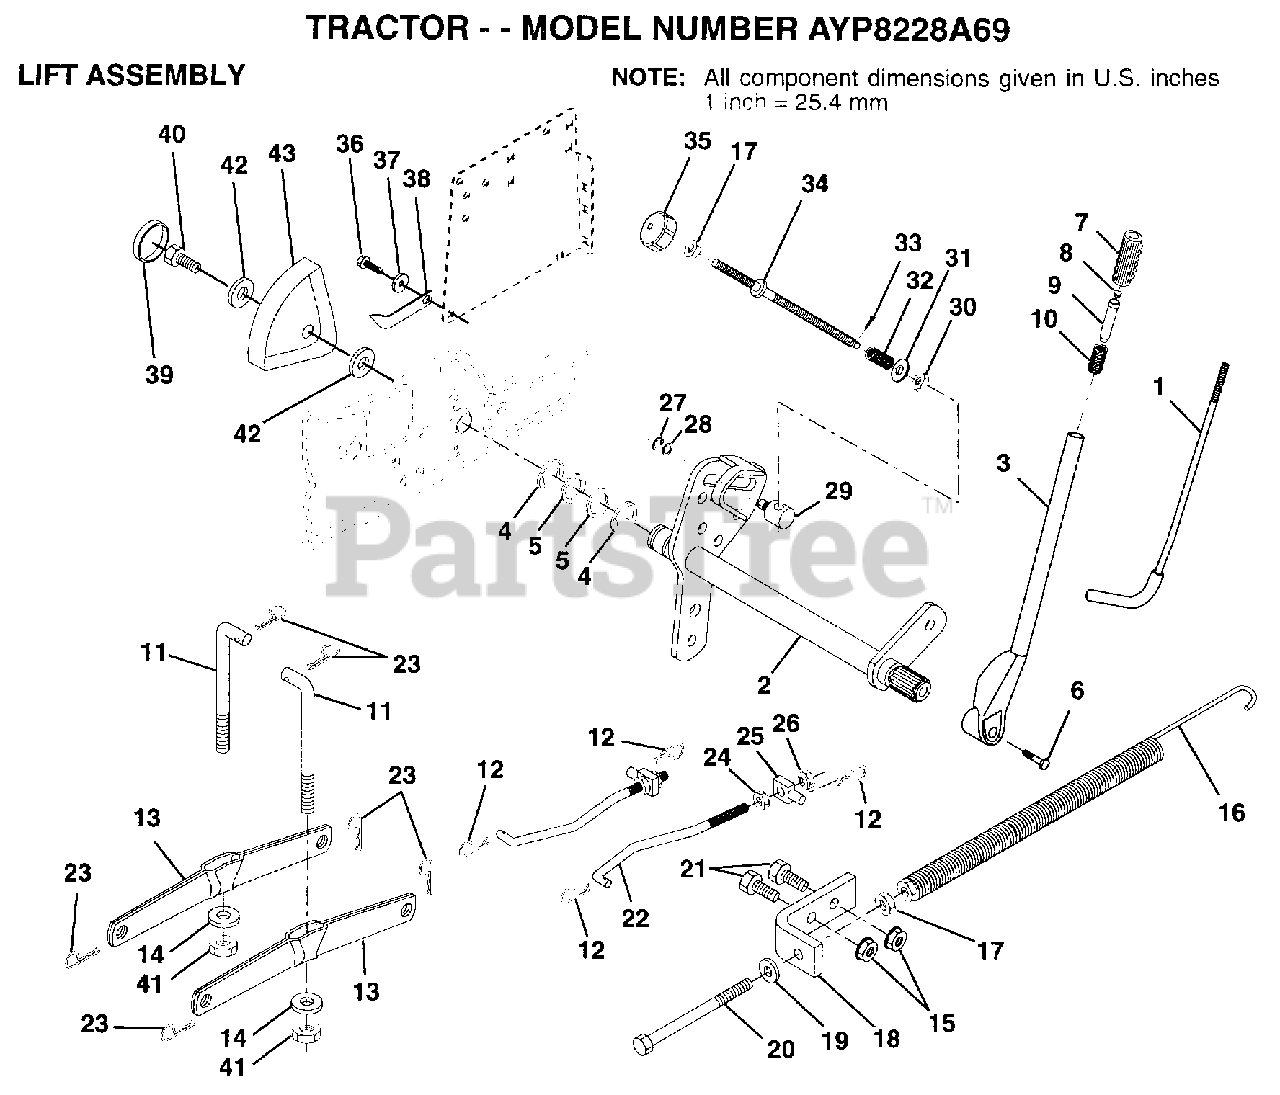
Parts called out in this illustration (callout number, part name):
1	LEVER ROD LT
2	SHAFT.LIFT.VGT.95
4	E-RING
5	WASHER
6	"BOLT,HEX"
7	GRIP HANDLE
10	SPRING T
11	LINK.LIFT.MWR.VGT
12	RETAINER.SPRING
13	ARM SUSP REAR
14	BEARING PVT LH
17	NUT
18	BRACKET SPRING AS
19	WASHER
20	BOLT-ADJ SPRING T
21	BOLT
22	LINK.FRONT
24	NUT
25	TRUNION
26	NUT.LK.W/WSH.1/2.
27	KLIP RING
28	WASHER
29	TRUNION LT
30	NUT T
31	WASHER
32	SPRING.COMP.INF.H
34	ROD.ADJ.LIFT
35	KNOB INF 3/8-16
36	SCREW
37	WASHER T
38	POINTER HGT IND
39	"PLUG,HOLE"
40	SCREW
41	NUT.CROWNLOCK.3/8
42	WASHER
43	HEIGHT INDICATOR
